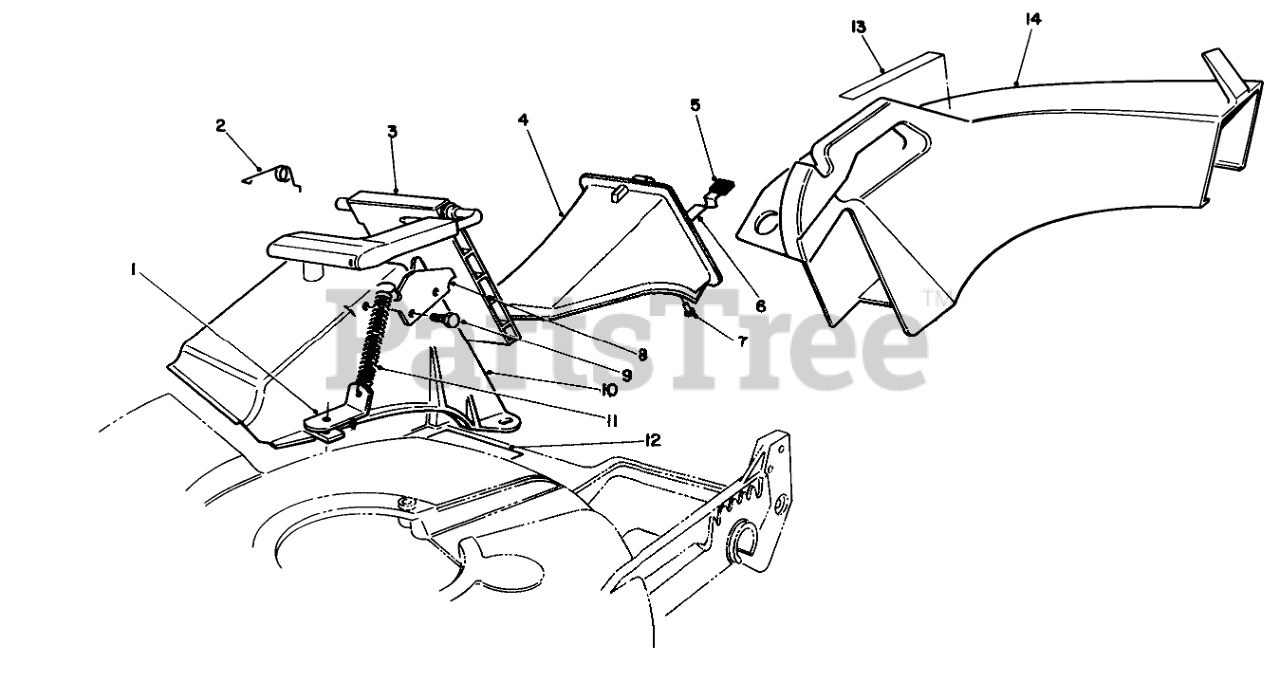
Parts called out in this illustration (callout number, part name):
1	Bracket-Spring
2	RETAINER-DOOR
3	DOOR ASSEMBLY
4	Plug Assembly (Incl. Ref. #5-7)
5	GRIP-LATCH
6	LATCH-PLUG, DISCHARGE
7	RIVET-HEAD, FLAT
8	DOOR LATCH PLATE
9	SCREW-PLASTITE
10	DISCHARGE TUNNEL
11	SPRING-DOOR
12	DECAL - CAUTION
13	DECAL - WARNING
14	Chute-Discharge (Incl. Ref. #13)
